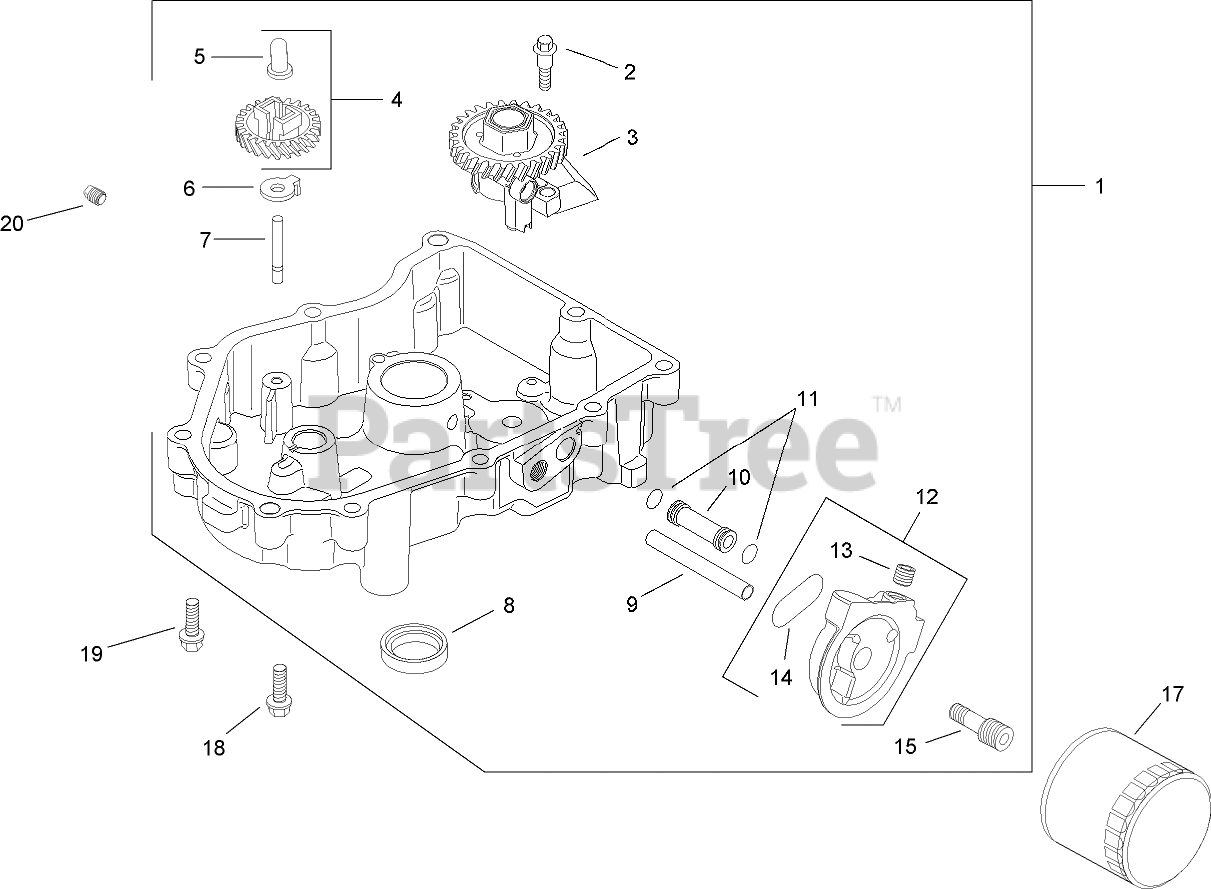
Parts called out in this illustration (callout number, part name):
1	Oil Pan ASM (Includes2-15)
2	SCREW-SHOULDER, THD FRM (M6x1.0x26.5)
3	Oil Pump ASM
4	Governor Gear Kit w/Pin (Includes5)
5	PIN-REGULATING, GOVERNOR
6	TAB-LOCKING
7	SHAFT-GEAR, GOVERNOR
8	SEAL-OIL (P-T-O END)
9	TUBE-FEED, OIL (FILTER TO PAN)
10	TUBE-FEED, OIL (PAN TO FILTER)
11	O-RING
12	Adapter-Oil Filter (Includes13-14)
13	PLUG-PIPE, COUNTERSUNK (1/8)
14	O-Ring-Oil Filter Adapter
15	NIPPLE-FILTER, OIL
17	Filter-Oil
18	SCREW-FLANGE (M8X1.25X45)
19	Screw-HF (M8x1.25x45)
20	PLUG-PIPE, SQ HD (3/8)
